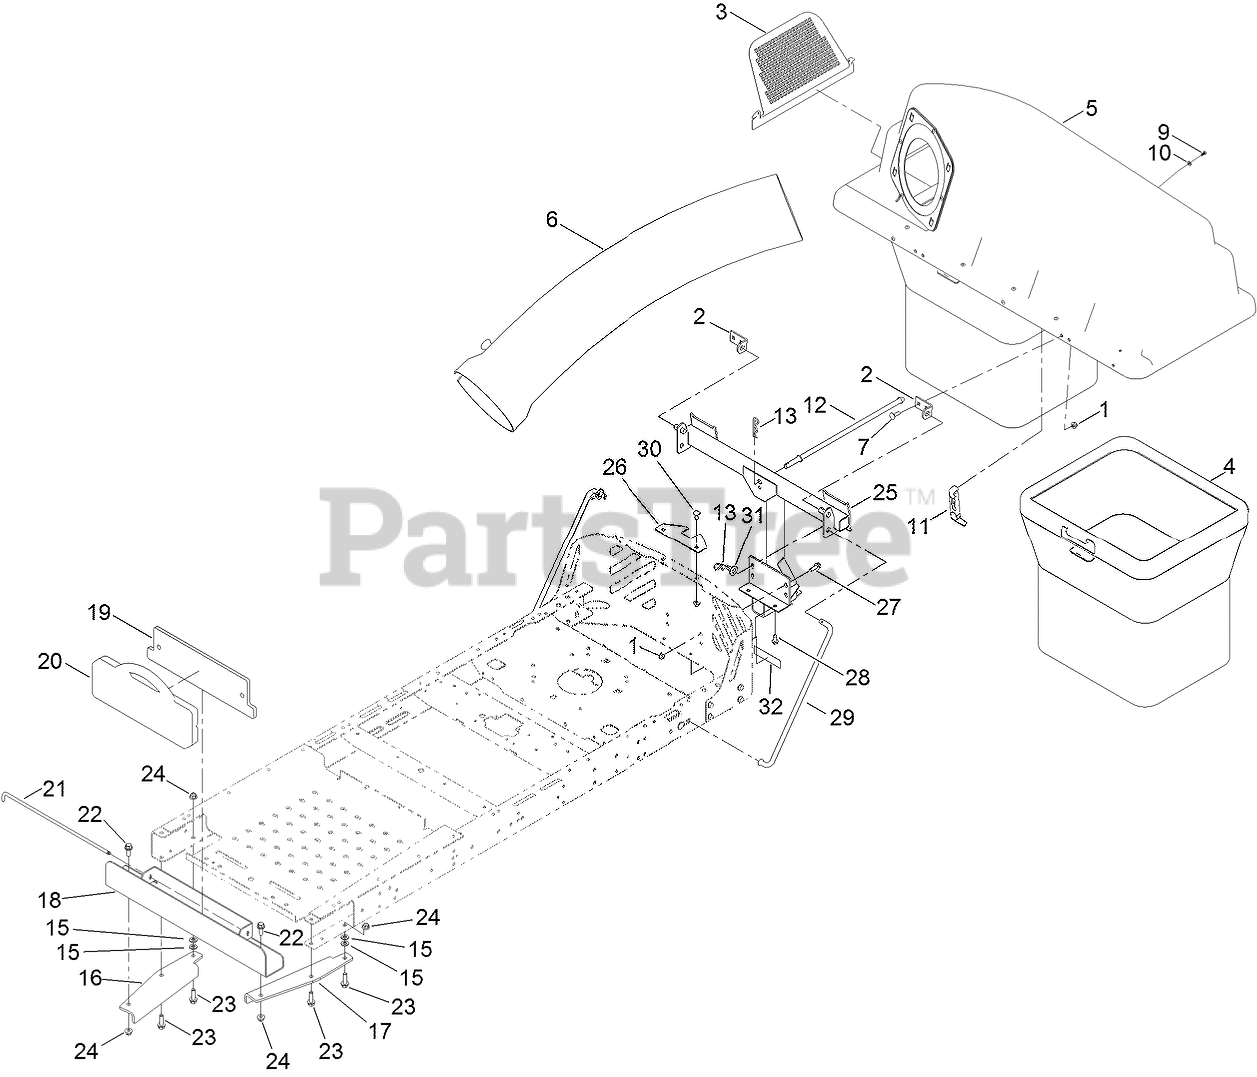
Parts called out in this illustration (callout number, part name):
1	NUT-HF
2	BRACKET-HOPPER PIVOT
3	SCREEN-BAGGER
4	BAG ASM
5	BAGGER TOP ASM
6	TUBE-BAGGER
7	BOLT-CARR
9	SCREW-PLASTIC, PTH
10	WASHER-PLAIN
11	LATCH-RUBBER
12	ROD-HOOD, DOWN (HOLD)
13	PIN-HAIR
15	WASHER-FLAT
16	BRACKET-BAGGER WEIGHT, RH
17	BRACKET-BAGGER WEIGHT, LH
18	CHANNEL-WEIGHT, BAGGER
20	WEIGHT-35 POUND
21	PIN-WEIGHT
22	SCREW-HHF
23	SCREW-HHF
24	NUT-HF, NI
25	PIVOT FRAME ASM
26	BRACKET-STABILIZER
27	SCREW-HHF
28	SCREW-HWHTF
29	ROD-SUPPORT, CZ
30	BOLT-CARR
31	WASHER-FLAT
